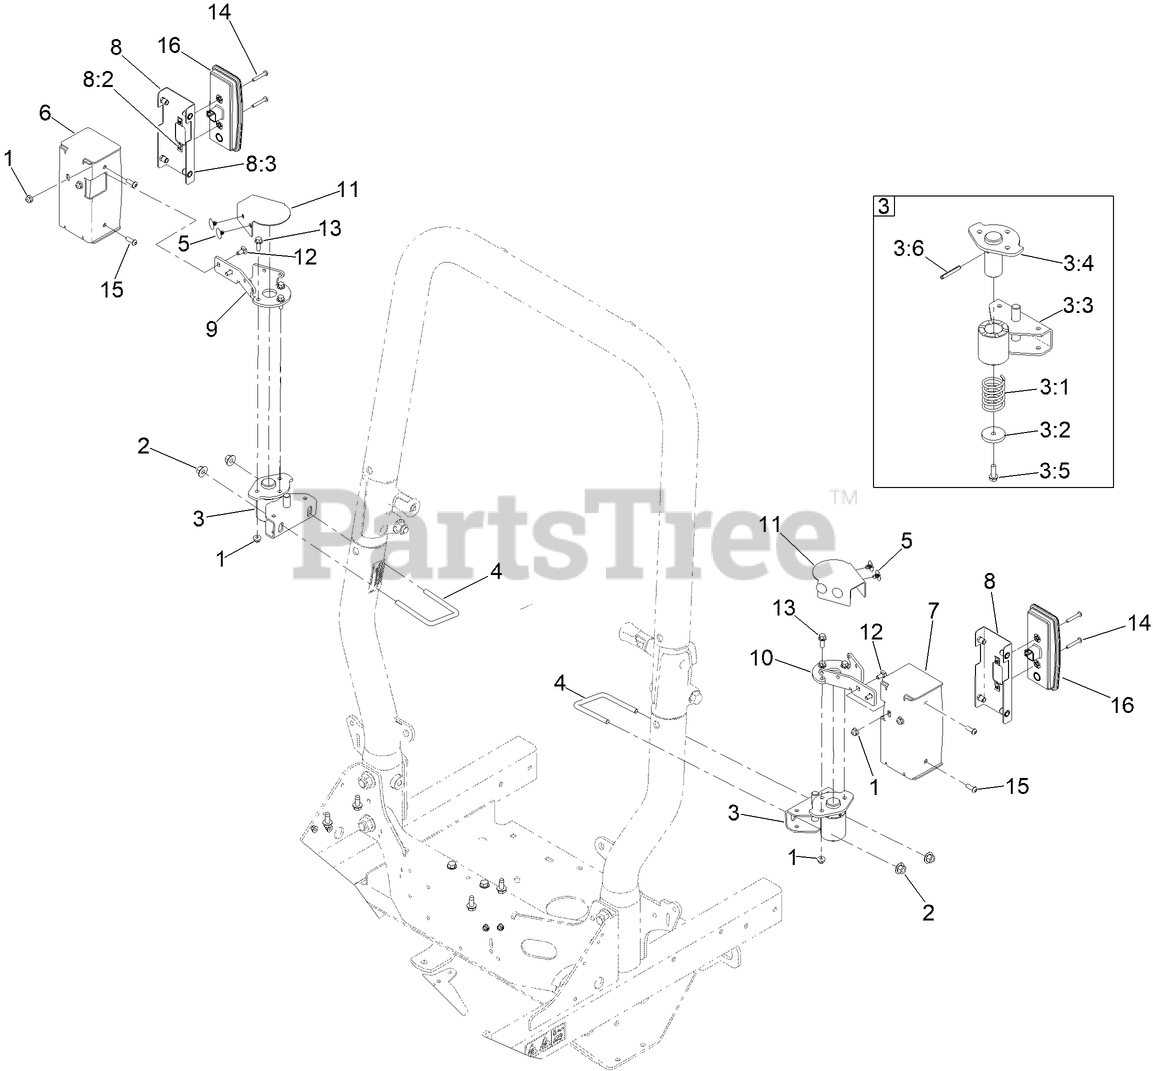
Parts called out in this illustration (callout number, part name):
1	NUT-HF
3	BRACKET-PIVOT, ASM
3:1	SPRING-COMPRESSION
3:2	WASHER 34 DIA X 7 DIA X 5 THK
3:3	PIVOT BRACKET Z2000 [BLACK]
3:5	SCREW-HWH
3:6	PIN-ROLL
4	U-BOLT
5	RIVET-PLASTIC
6	HOUSING-LIGHT, RH
7	HOUSING-LIGHT, LH
8	INNER MOUNT ASM
8:2	NUT-SPEED
8:3	NUT-CLINCH, HEX
9	MOUNT-LIGHT, RH
10	MOUNT-LIGHT, LH
11	COVER-MOUNT
12	SCREW-CARR
13	SCREW-HHF
14	SCREW-PPH
15	SCREW-HSBH
16	LIGHT-REAR TAIL/STOP/TURN
